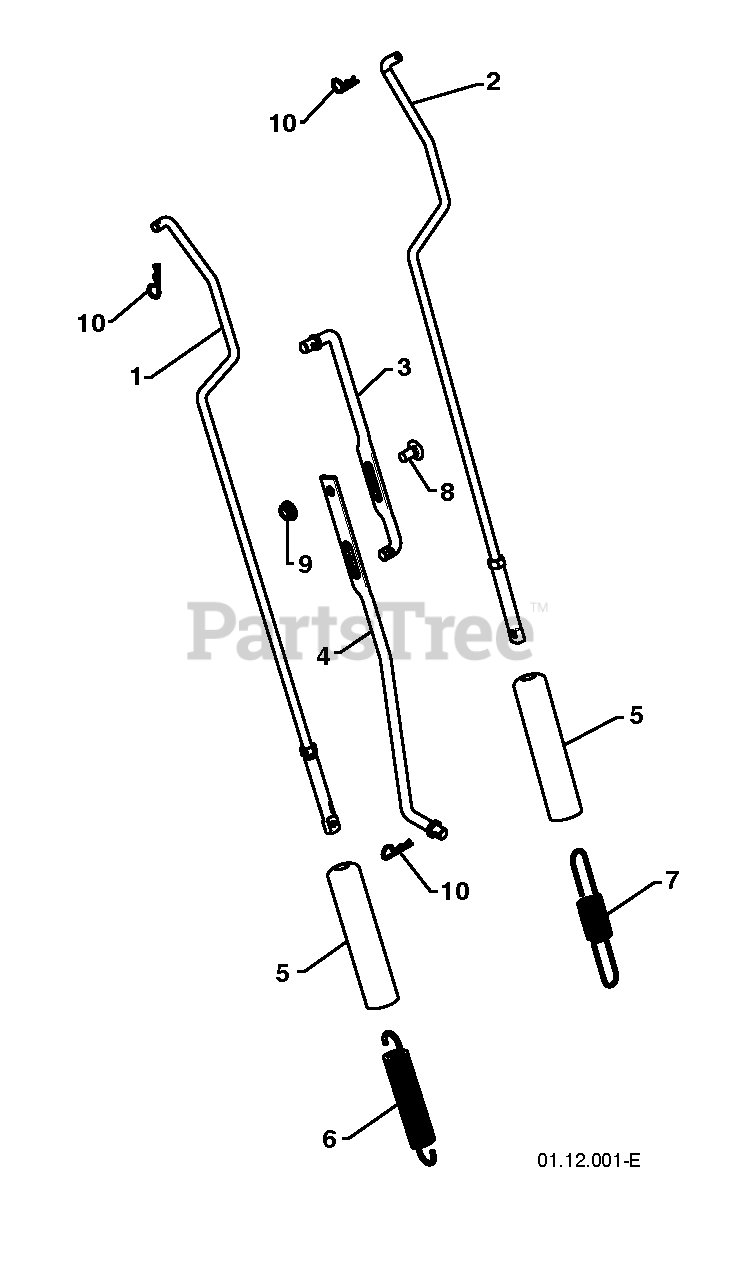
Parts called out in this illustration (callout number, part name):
1	ROD.AUGER.CONTROL
2	ROD.CONTROL.TRACTION.
3	ROD, UPPER SPEED CONTROL
4	ROD, LOWER SPEED CONTROL
5	SLEEVE, SPRING
6	SPRING, AUGER CONTROL
7	SPRING, TRACTION DRIVE
8	BOLT
9	NUT.FLANGE.5/16
10	SPRING RETAINER
